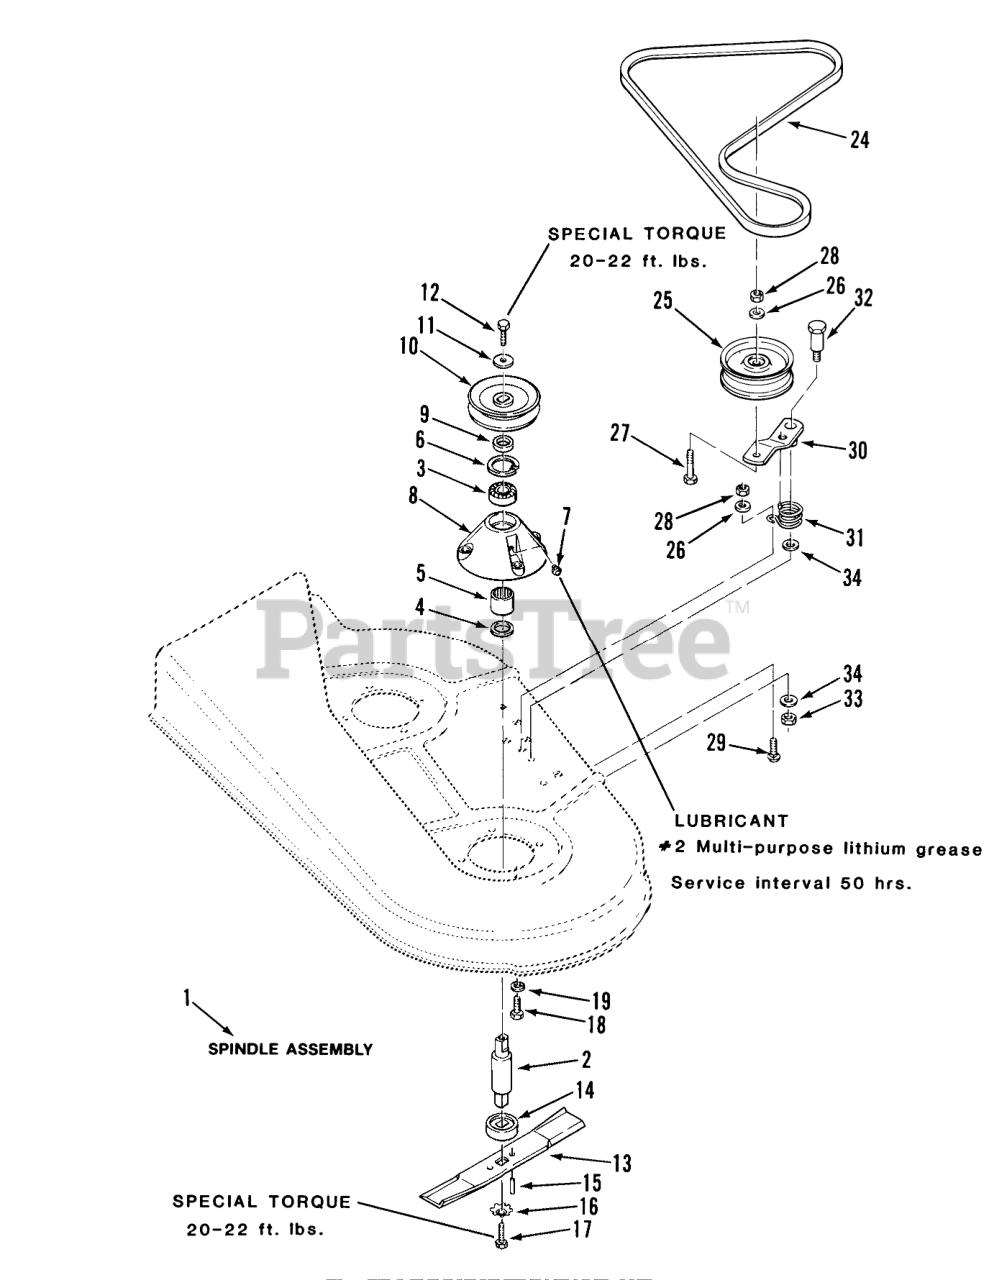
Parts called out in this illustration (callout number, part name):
1	Spindle Assembly (Includes Items 2 Thru 8)
2	SPINDLE MOWER
3	BEARING-BALL
4	OIL SEAL
5	BEARING-NEEDLE
6	INT SNAP RING
7	Fitting-Grease
8	HOUSING
9	SPACER
10	PULLEY-BLADE
10	PULLEY BLADE
11	WASHER
12	Bolt
13	S/A BLADE KIT
14	Spindle Cup
15	SPIROL ROLL PIN
16	WASHER
17	Bolt
18	Bolt
19	LOCKWASHER
24	V-BELT
25	PULLEY-IDLER
26	Washer
27	Bolt
28	Nut
29	Bolt
30	Idler Arm
31	SPRING-TORSION
32	BOLT-SHOULDER
33	NUT-JAM(7/16-14)
